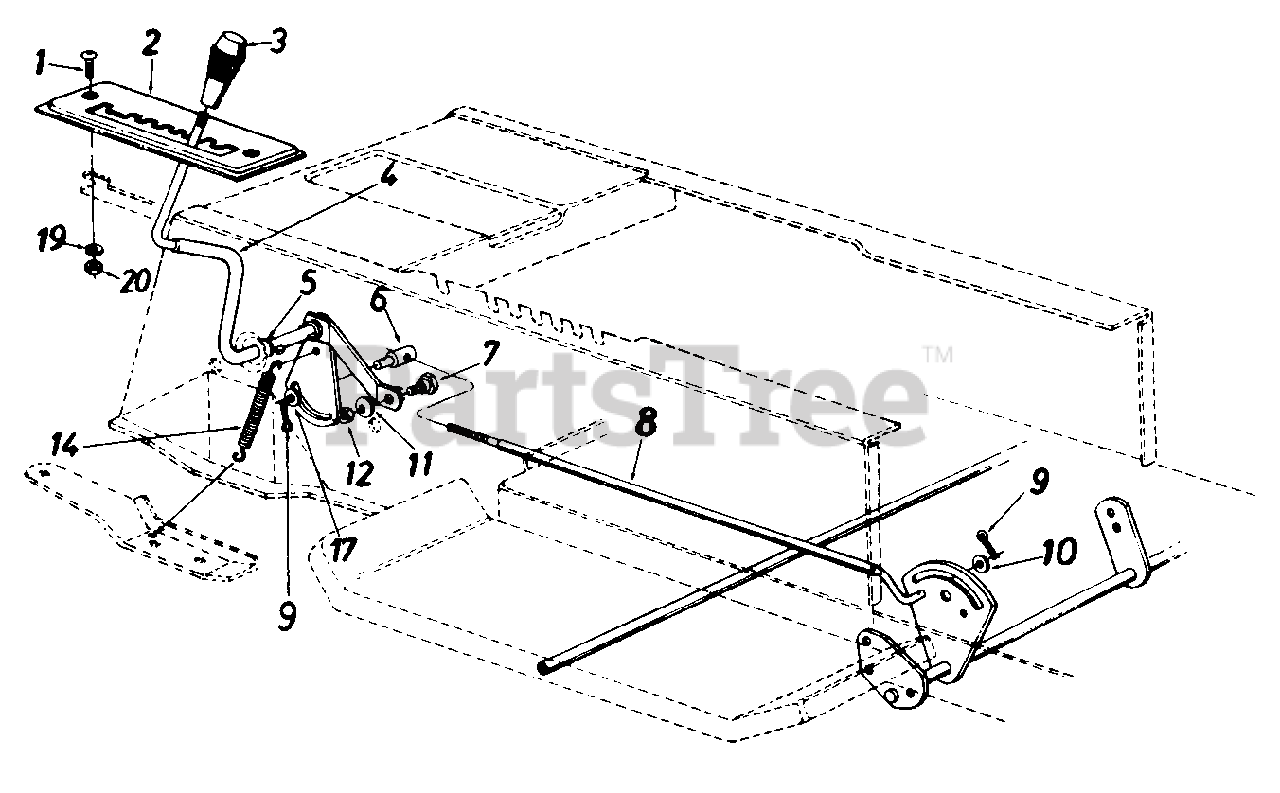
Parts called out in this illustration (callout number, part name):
1	Truss Mach. Scr. 1/4-20 X .75" Lg.
4	Speed Selector Cam Ass'y.
5	Flat Washer .53" I.D. x .93"
6	Ferrule 3/8-24 x .37" Dia.
7	Shoulder Bolt
8	Speed Control Link
9	Cotter Pin 3/32" Dia. x 1.0"
10	Fl-Wash. .469" I.D. x .88n
11	L-Wash. 5/16 I.D.
12	Hex Nut 5/16-18 Thd.
14	Spring .38" O.D. x 3.18" Lg.
17	Fl-Wash. .385" I.D. x .62"
19	L-Wash. 1/4" l.D.
20	Hex Nut 1/4-20 Thd.
